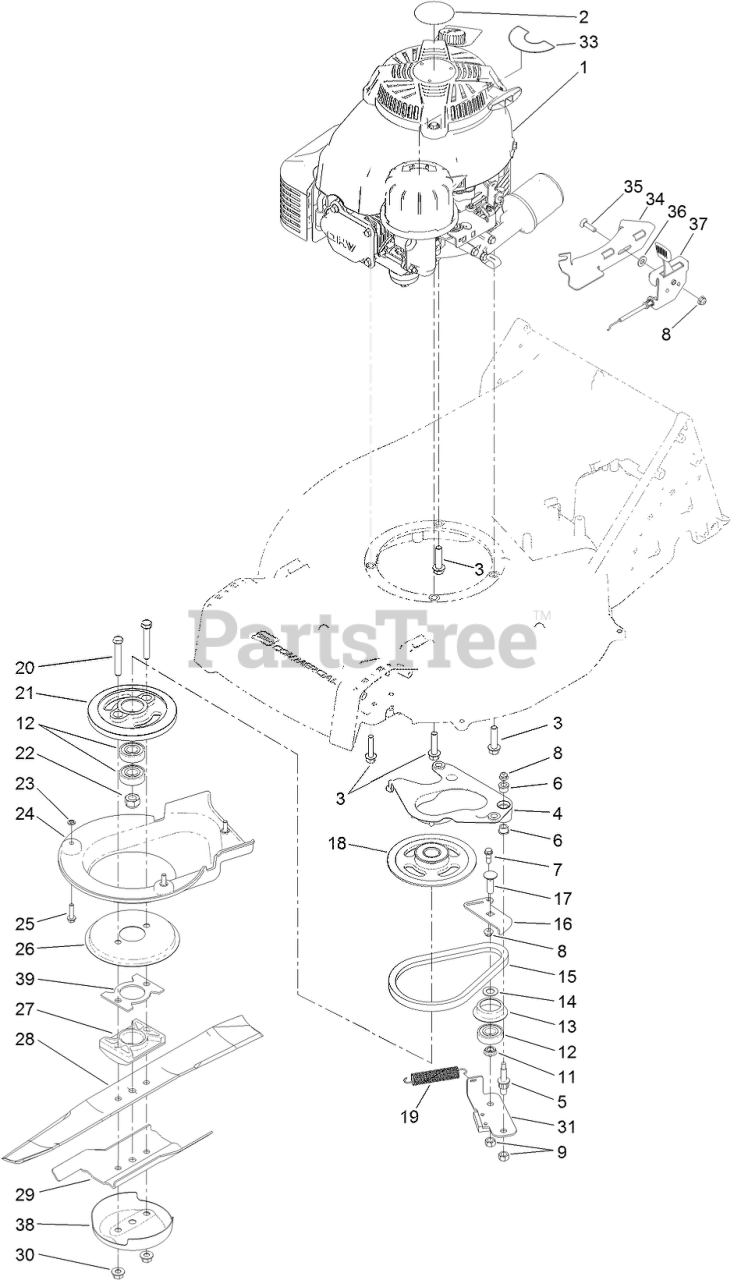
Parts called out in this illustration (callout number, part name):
1	ENGINE-KAWASAKI, FJ180V
3	SCREW-HWH
4	PLATE-ANCHOR
5	BOLT-SHOULDER
6	BUSHING-FLANGE
7	BOLT-SHOULDER
8	NUT-HF
9	NUT-HEX
11	SPACER-BEARING
12	BEARING-BALL
13	RETAINER-BELT
14	WASHER-PLAIN
15	BELT
16	PLATE-GUIDE, BBC
17	BOLT-CARR
18	PULLEY
19	SPRING-TENSION, BRAKE
20	SCREW-HH
21	DRUM
22	NUT-HEX
23	NUT-RETAINER
25	SCREW-HWHTF
26	DISC
27	SUPPORT-BLADE
28	BLADE-RECYCLING
29	ACCELERATOR-BLADE
30	NUT-FLANGE, LOCK
31	PLATE-BRAKE
34	BRACKET-MOUNT, THROTTLE
35	SCREW-CARR
36	WASHER-PLAIN
37	THROTTLE
38	CUP-ANTI SCALP
39	SPACER-DRIVER, BLADE
